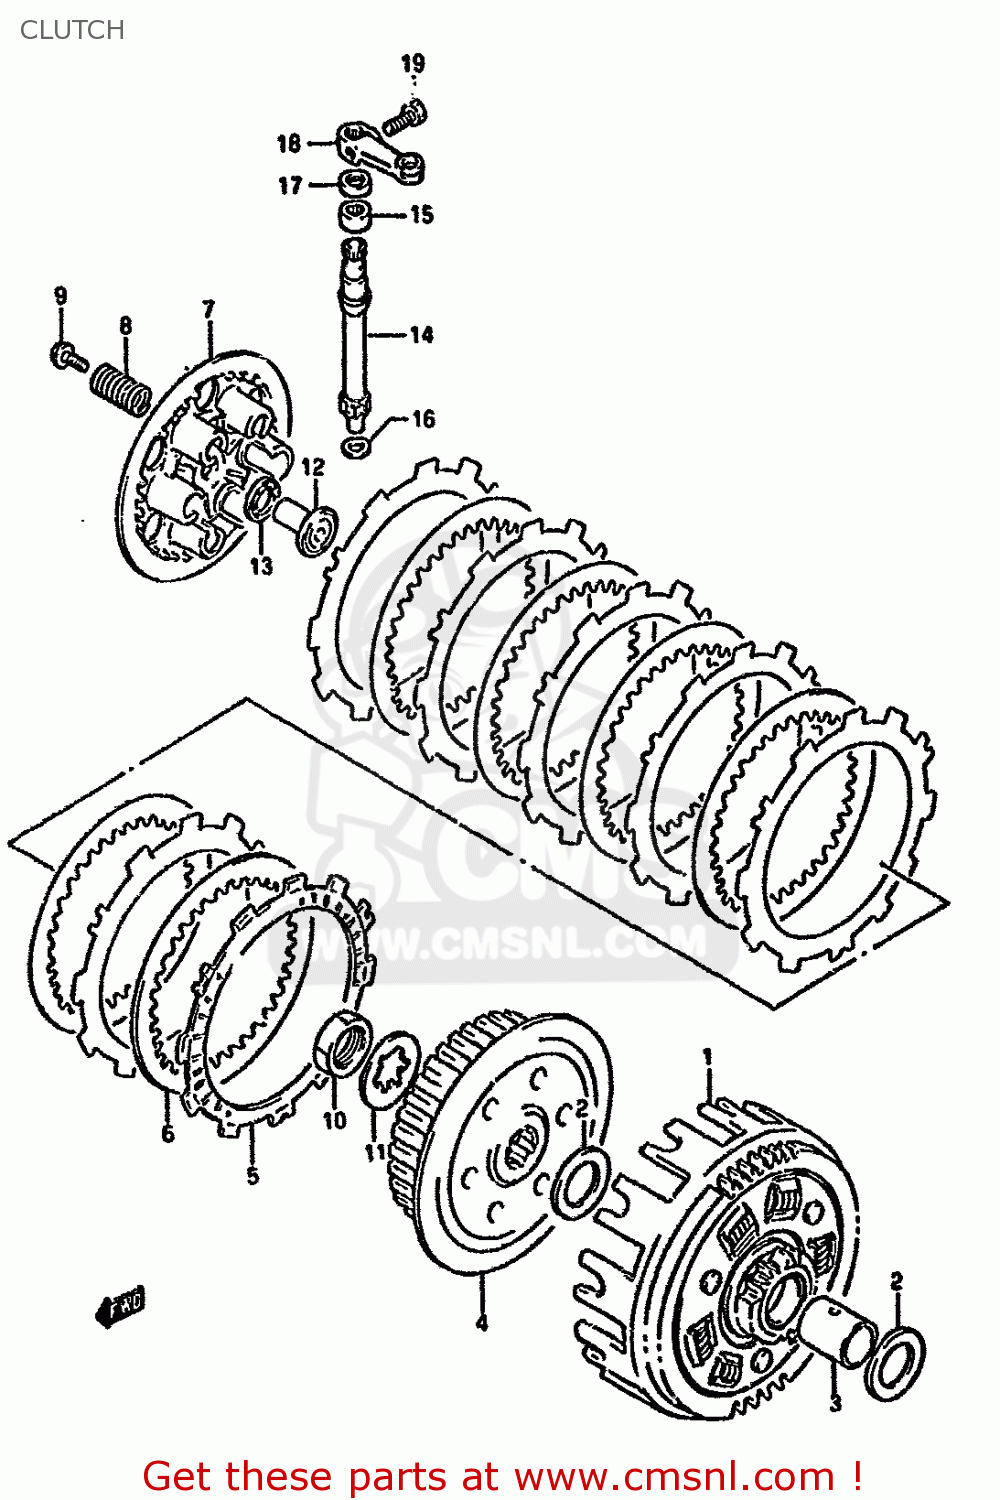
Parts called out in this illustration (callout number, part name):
1	GEAR ASSY,PRI DRIVEN(62/15
2	WASHER
3	SPACER(20X25X29)
4	HUB,CLUTCH SLEEVE
5	PLATE,CLUTCH DRIVE (NAS)
6	PLATE,CLUTCH DRIVEN (NAS)
7	DISC,CLUTCH PRESSURE
8	SPRING
9	BOLT 5X16
10	NUT (20MM)
11	WASHER,LOCK
12	RACK,CLUTCH RELEASE
13	BEARING(10X22X2.8)
14	PINION,CLUTCH RELEASE
15	BEARING(12X16X10)
16	WASHER
17	SEAL,OIL(10X17X5)
18	ARM,CLUTCH RELEASE
19	BOLT
